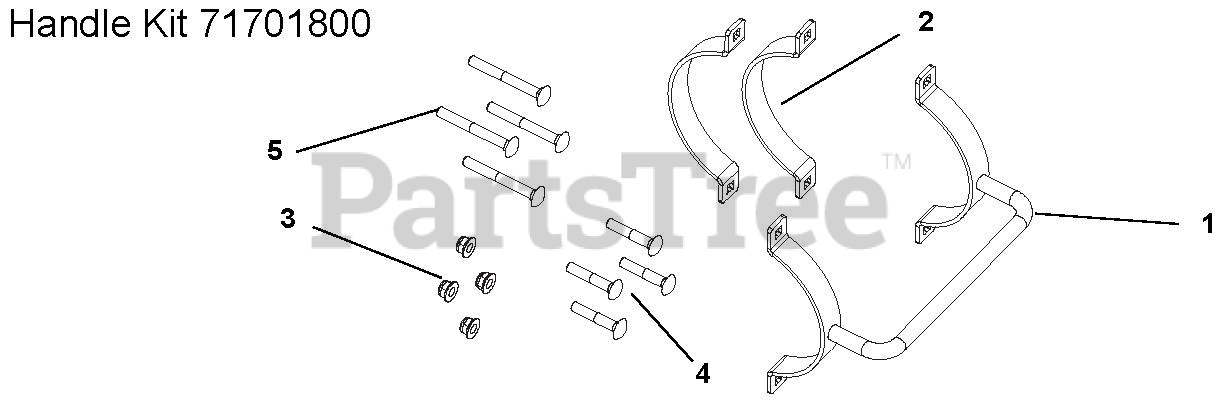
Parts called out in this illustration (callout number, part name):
1	WDMT, HYD. CYLINDER CLAMP
2	BRKT, CYLINDER CLAMP
3	@BLT-HEX .38-16X1.25 GR5 YWZC
4	BLT-RDHDSQNK .31-18X2.75 G5YZ
5	@BLT-RDHDSQNK .31-18X1.75 G5YZ
